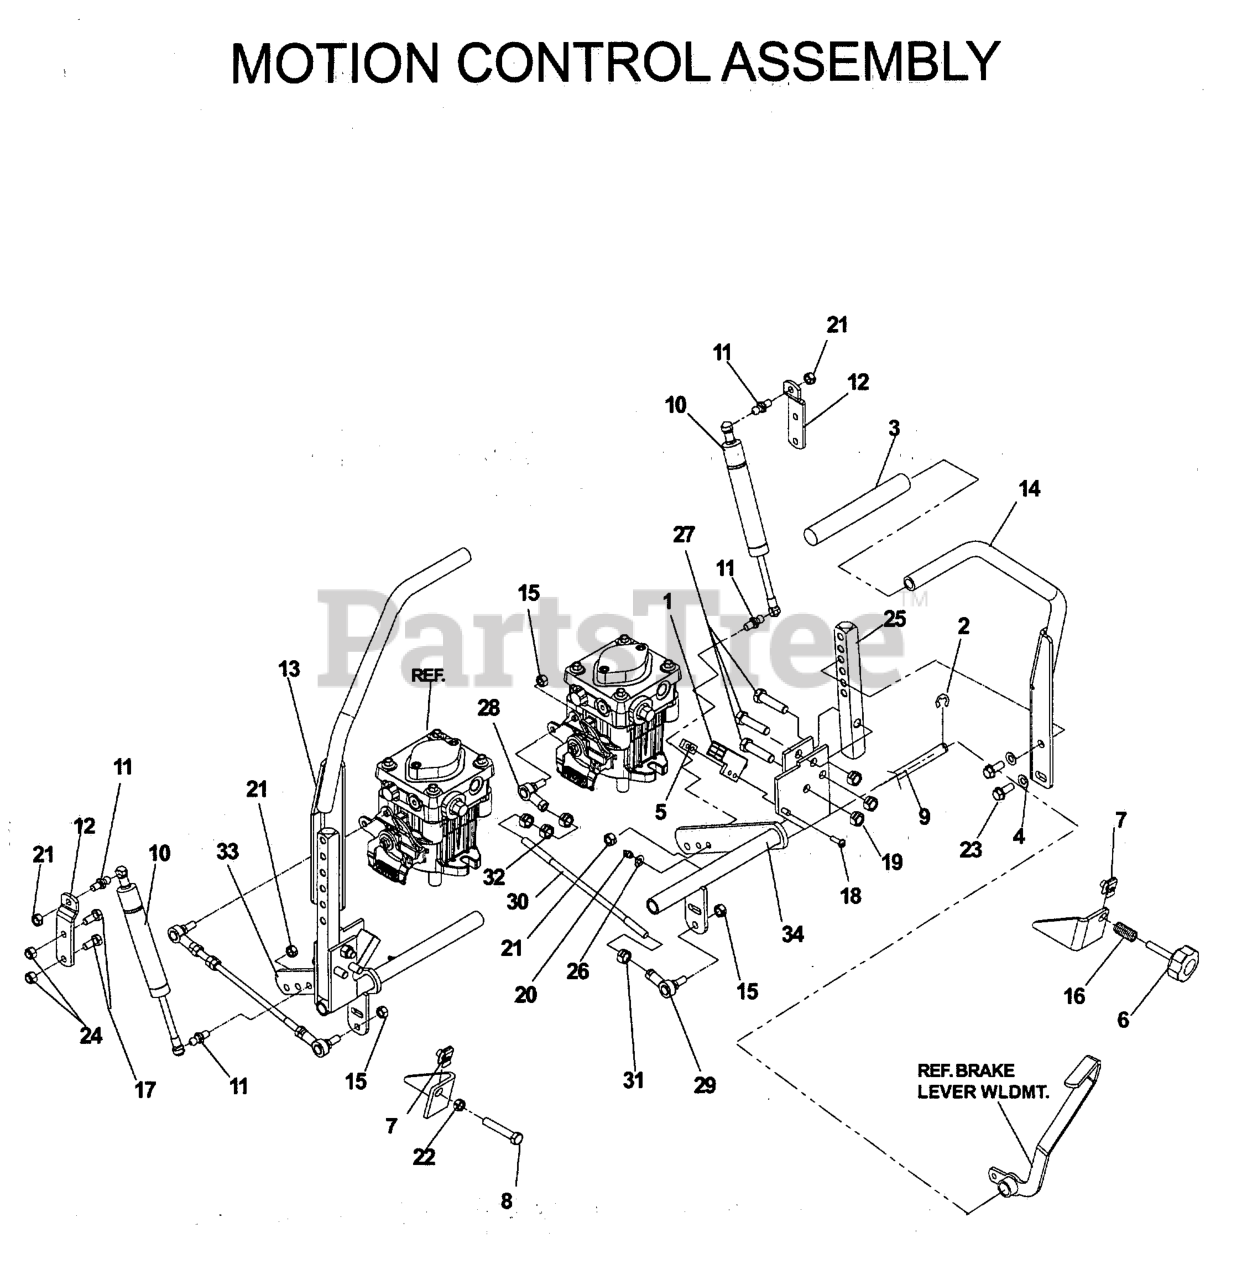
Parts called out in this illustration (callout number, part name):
1	SWITCH, INTERLOCK
2	E-RING 1/2 (2 2)
4	WASHER, 3/8 DISC SPRING SPEC
5	TAPPED PLATE
6	ADJUSTMENT KNOB
7	U-CLIP 5/16-18 NUT RETAINER
8	HCS 5/16-18X1-3/4 TPBLT
9	CONTROL SHAFT
10	DAMPENER
11	STUD.BALL.10MM
12	DAMPENER ARM
13	RT DRIVE LEVER WLDMT
14	LT DRIVE LEVER WLDMT
15	NUT 5/16F NYLOC
16	COMPRESSION SPRING
17	HCS 5/16C X 3/4
18	SCREW #10-24 X 5/8
19	NUT 3/8-16 NYLOC
20	ZERK
21	NUT 5/16C CENTERLOCK
22	NUT 5/16C HEX
23	HCS 3/8-16X1.GRD.5.ZD
24	NUT 5/16 NYLOC
25	CONTROL ARM
27	HCS 3/8-16 X 1 3/4 GR5
28	SPHERICAL ROD END, RH
29	SPHERICAL ROD END, LH
30	PUMP CONTROL LINK
31	NUT 5/16F LEFTHAND
33	DRIVE CONTROL, RT
34	DRIVE CONTROL, LT
